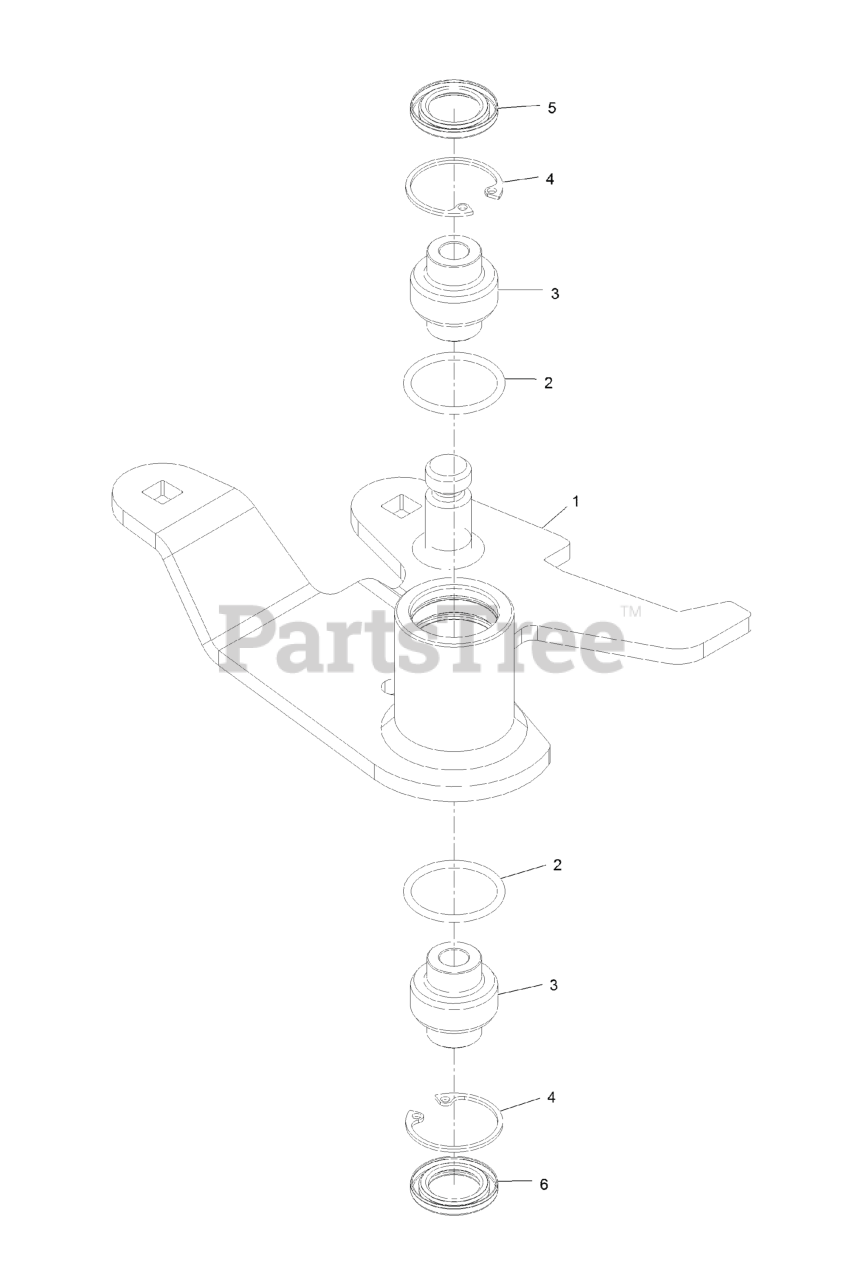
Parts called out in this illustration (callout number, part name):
1	ASM-Idler Arm, 96Rd [red]
3	BEARING-SPHERICAL
4	RING-SNAP
5	SEAL-LIP, SINGLE
6	SEAL-LIP, DOUBLE
